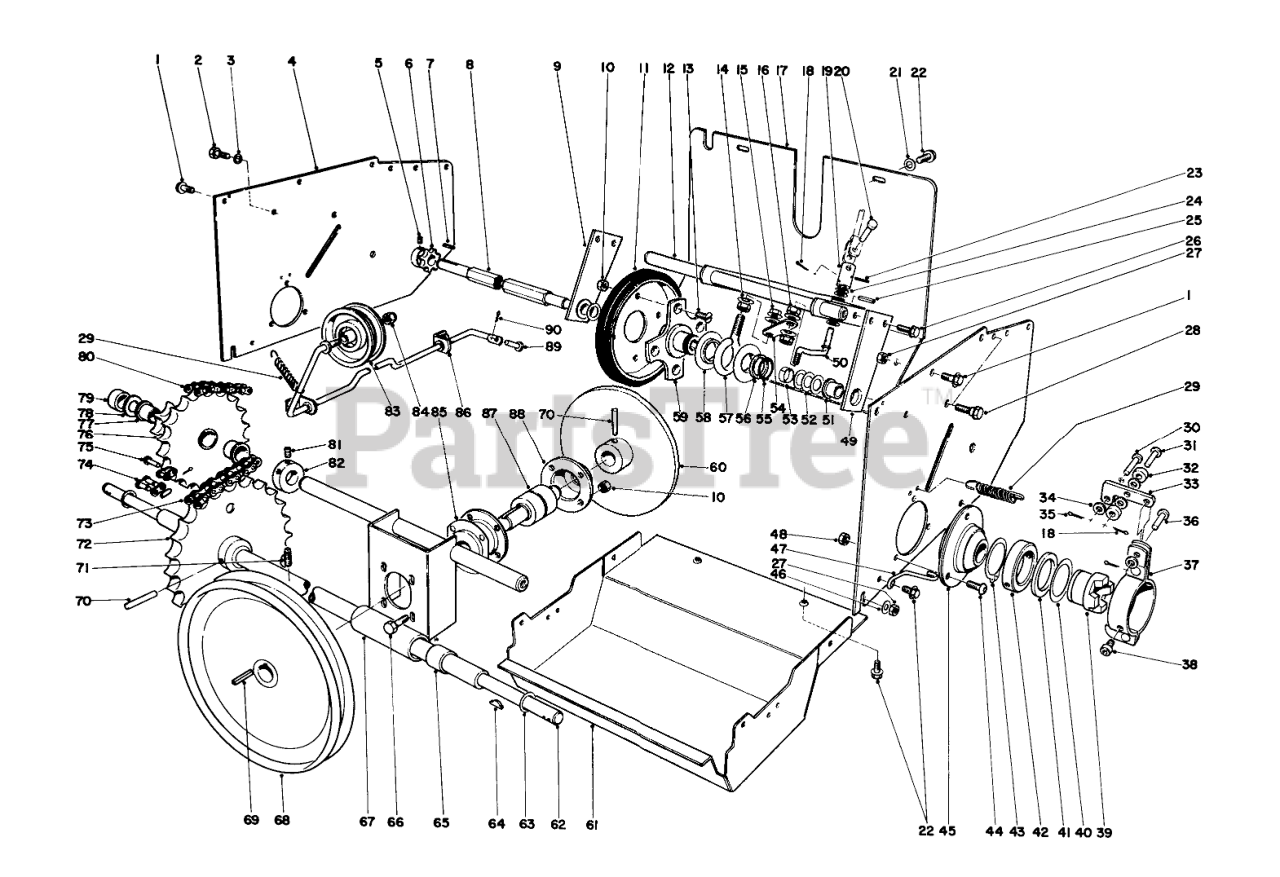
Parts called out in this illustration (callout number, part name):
1	SCREW-HHF
2	SCREW-HH
3	WASHER-LOCK
4	Side Plate
5	Set Screw
6	SPROCKET
8	FRICTION WHEEL SHAFT
9	Hex Shaft Mount Ass-y R.H. (Incl. Ref. 51)
10	Nut
11	Disc
12	Bracket Dead Shaft
13	5/16-18X5/8 FLT HD MS
14	WASHER-SPRING
15	NUT-LOCK, FLANGE
16	Nut
17	REAR COVER R
18	PIN-COTTER
19	U JOINT TUBE
20	CLEVIS PIN
21	WASHER-FLAT
22	Screw, Self-tapping
23	PIN-SPRING
24	Spacer
25	PIN-ROLL
26	Hex Hd. Screw
27	NUT-HEX
28	SHOULDER SCREW
29	EXTENSION SPRING
30	PIN-CLEVIS
31	PIN-CLEVIS
32	CLUTCH ROLLER
33	Arm Clutch
34	WASHER-FLAT
35	PIN-COTTER
36	PIN-CLEVIS
37	Clutch Mount Bracket
38	SCREW-HSH
39	Clutch Wheel
40	THRUST WASHER
41	THRUST BEARING
42	CLUTCH MOUNT COLLAR
43	RING-RETAINING, EXTERNAL
44	SCREW-HSBH
45	Bearing Flange
46	WASHER-FLAT
47	Clutch Retainer
48	NUT-LOCK
49	Hex. Shaft Mount Ass-y L.H. (Incl. Ref. 51)
50	CONNECTION ROD
51	BUSHING
52	WASHER-FLAT
53	SPLIT SPACER
54	SHIFT ROD PIVOT
55	RING-RETAINING
56	WASHER-THRUST
57	SLIDER RING COLLAR
58	SLIDER RING
59	Hub Traction Disc
60	FRICTION PLT WA
61	LOWER SHIELD R
62	Axle Shaft
63	WASHER
64	1/4X1-1/16 HI-PRO KEY
65	Bushing
66	SCREW-HH
67	Bulkhead (Incl. Ref. 65)
68	Pulley
69	KEY-SQUARE
70	Groove Pin
71	SCREW-SET, SQH
72	Sprocket
73	Chain Lower
74	LINK-CONNECTING
75	1/4 OFFSET LINK
76	Sprocket Hub (Incl. Ref. 77)
77	3/4ID X 3/4LG BSHG
78	WASHER-THRUST
79	Spacer Idler
80	1/4 X 42 CHAIN W/LINK
81	SCREW-HSH
82	Collar
83	PULLEY-IDLER
86	Clutch Rod
87	Friction Plate Shaft
88	HOUSING BEARING
89	PIN-CLEVIS
90	PIN-COTTER
